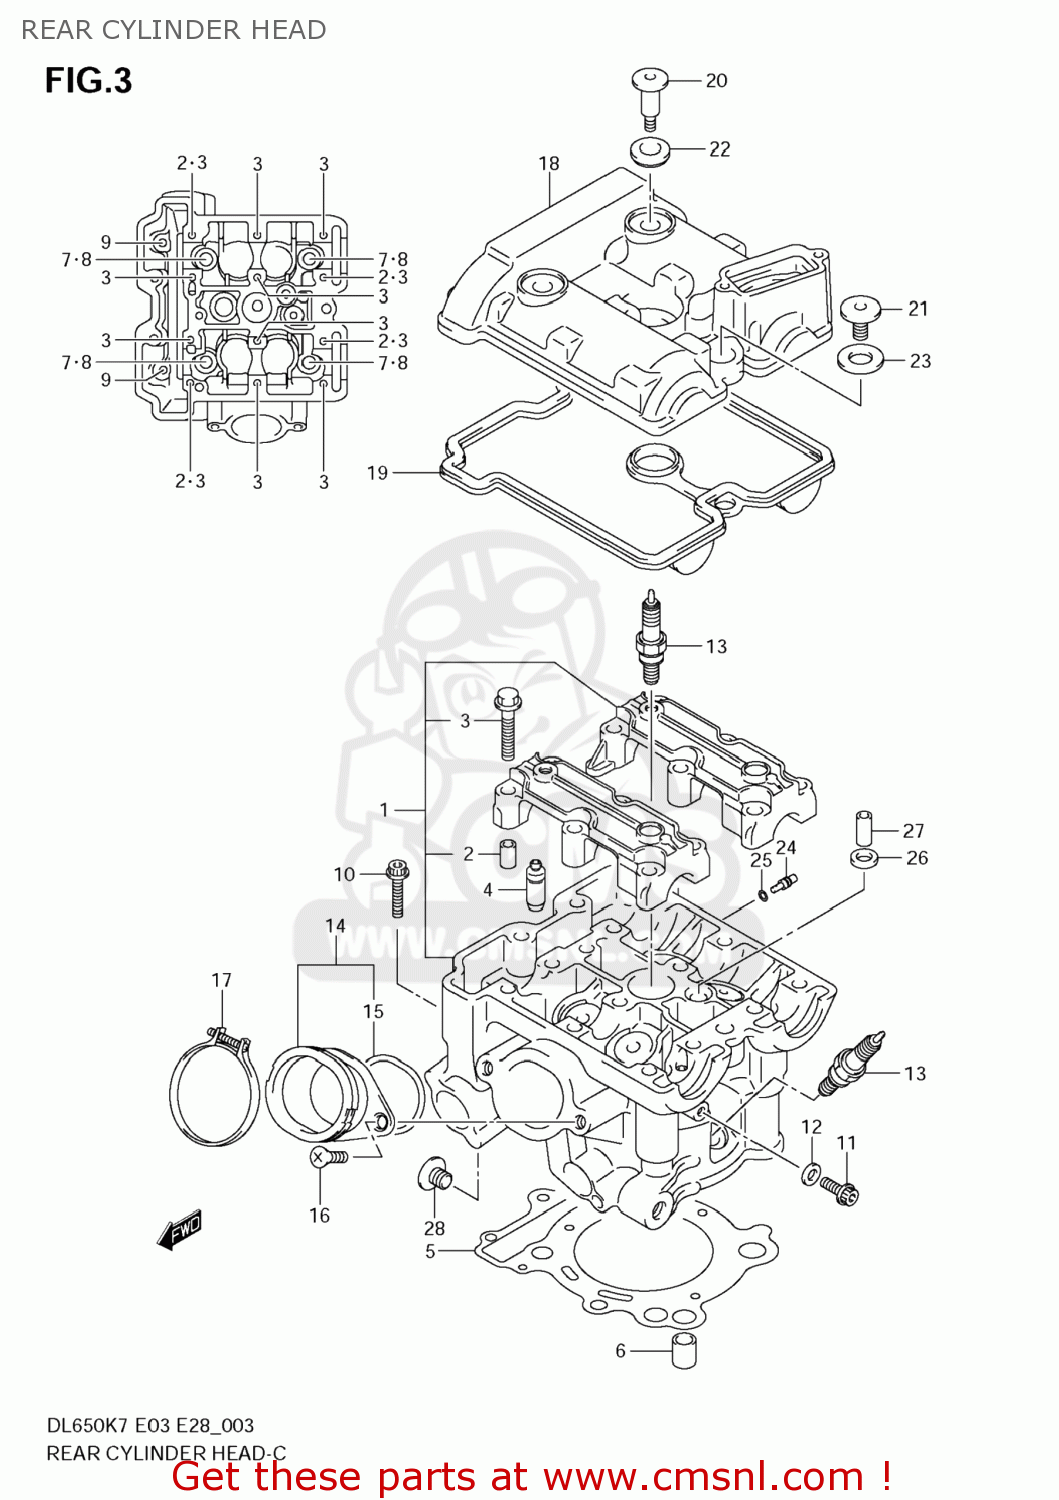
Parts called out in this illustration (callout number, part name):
1	HEAD ASSY,CYLINDER RR
2	PIN(6.2X8X11)
3	BOLT(6X39)
4	GUIDE,VALVE
5	GASKET,CYLINDER HEAD (NAS)
6	PIN
7	WASHER(10.5X19X2)
8	BOLT(10X160)
9	BOLT(6X70)
10	BOLT
11	BOLT
12	GASKET(5.8X13X1.2) (NAS)
13	PLUG,SPARK(CR8E)
14	PIPE ASSY,INTAKE RR
15	O RING(D:2.4,ID:47X42)
16	SCREW
17	CLAMP
18	COVER,CYLINDER HEAD RR
19	GASKET,CYLINDER HEAD COVER (NAS)
20	BOLT(7X17.5)
21	BOLT(7X31)
22	WASHER,CYL HEAD COVER
23	CUSHION,HEAD COVER BOLT
24	JET(8)
25	O RING(D:1.2,ID:4)
26	GASKET,2ND AIR PASSAGE (NAS)
27	PIN(6.2X8X16)
28	CAP,ENGINE MOUNTING
